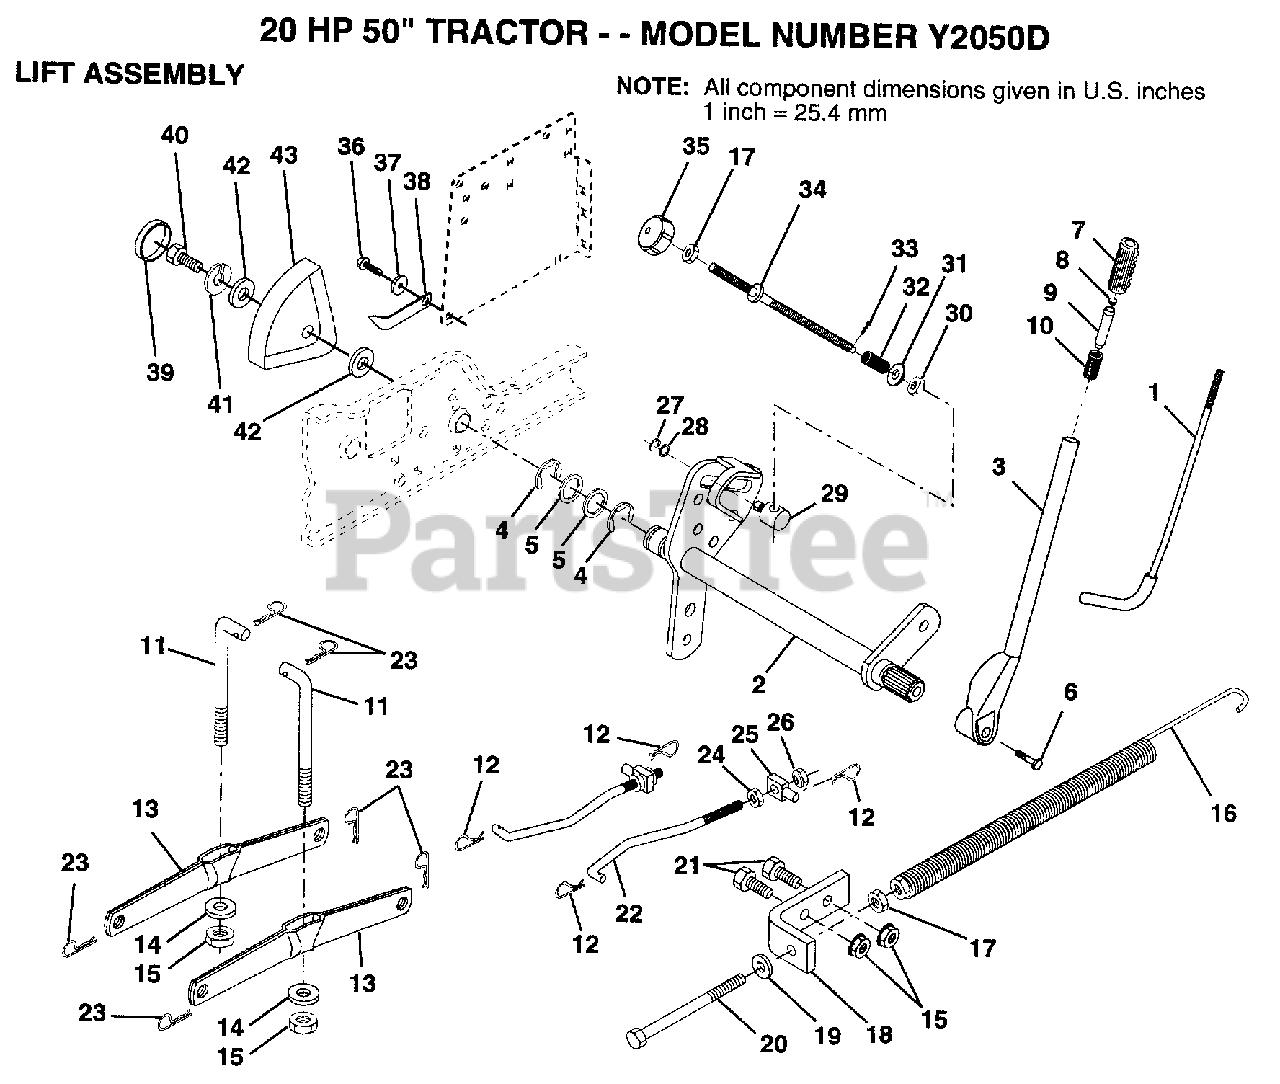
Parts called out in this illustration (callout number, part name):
1	LEVER ROD LT
4	E-RING
5	WASHER
6	"BOLT,HEX"
7	GRIP HANDLE
10	SPRING T
12	RETAINER.SPRING
14	BEARING PVT LH
15	NUT
17	NUT
18	BRACKET SPRING AS
19	WASHER
20	BOLT, ADJUST SPRING ASSIST
21	BOLT
22	LINK.FRONT
24	NUT
25	TRUNION
26	NUT.LK.W/WSH.1/2.
27	KLIP RING
28	WASHER
29	TRUNION LT
30	NUT T
31	WASHER
32	SPRING.COMP.INF.H
34	ROD.ADJ.LIFT
35	KNOB INF 3/8-16
36	SCREW
37	WASHER T
38	POINTER HGT IND
39	"PLUG,HOLE"
41	LOCKWASHER
42	WASHER
43	HEIGHT INDICATOR
